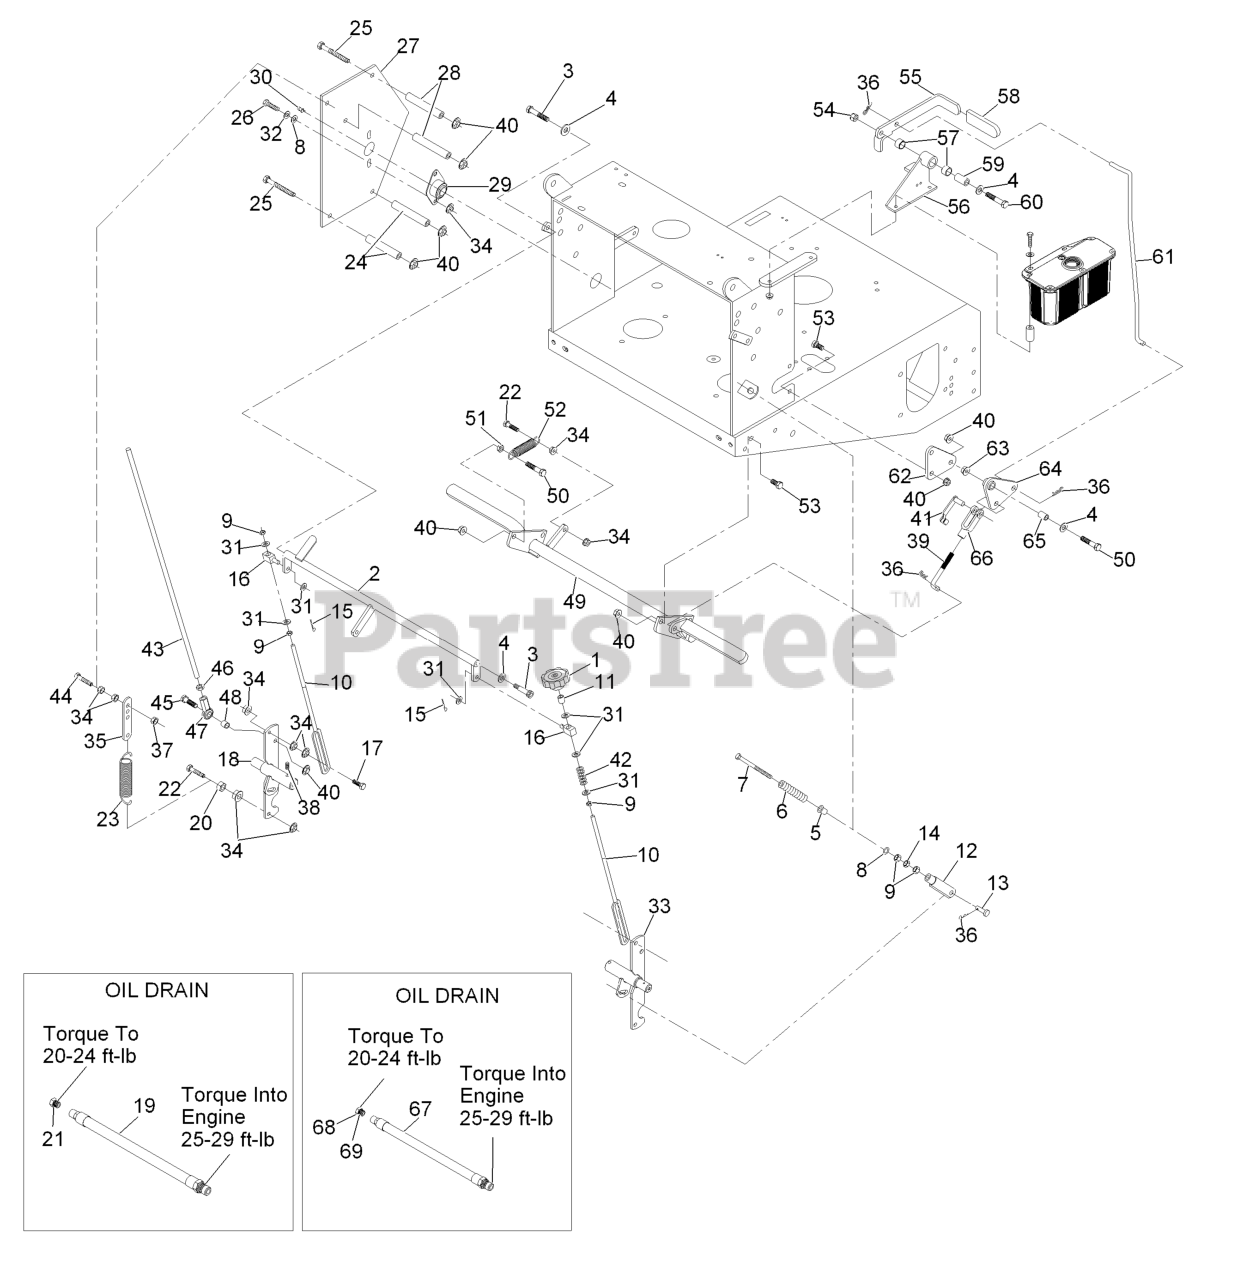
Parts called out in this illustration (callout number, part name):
1	KNOB-TRACKING
2	CRANK-CONTROL, SPEED
3	SCREW-HSH
4	WASHER-FLAT
5	BUSHING-FLANGED
6	SPRING,COMPRESSION (NEUT)
7	BOLT-RETURN, NEUTRAL
8	WASHER-FLAT
9	NUT-HEX
10	LINK-CONTROL, SPEED
12	YOKE-ADJUSTABLE
13	PIN-CLEVIS
14	NUT-JAM
15	PIN-COTTER
17	SCREW-HH
18	SHAFT-CONTROL, LH
20	NUT-JAM
22	SCREW-HH, SPECIAL
23	SPRING-EXTENSION
24	SPACER-SHIELD
25	SCREW-HH
26	SCREW-HH
27	SHIELD-CONTROL
28	SPACER-SHIELD
29	BEARING-FLANGE, SIDE
30	FITTING-GREASE
31	WASHER-PLAIN
32	WASHER-LOCK
33	SHAFT-CONTROL, RH
35	TAB-SPRING, EXTENSION
36	PIN-COTTER
37	NUT-LOCK, NI
38	SCREW-SET
39	LINKAGE-LOWER
40	NUT-HHF, WHIZ
41	PIN-SPRING, CLEVIS
42	SPRING-COMPRESSION
43	LINKAGE,DRIVE (PLT)
44	BOLT-TAP, HH
45	SCREW-HH
46	NUT-HEX JAM, LH
47	JOINT-BALL END, LH
48	SPACER-TUBE, PUMP LINK
50	SCREW-HH
51	NUT-JAM
52	SPRING-IDLER
53	SCREW-HH
54	NUT-LOCK, NI
55	LEVER,PARK BRK W/DECAL
56	BRACKET ASM
57	SLEEVE-BUSHING
58	GRIP-LEVER
59	BUSHING-PIVOT
60	SCREW-HH
61	LINKAGE-UPPER
62	BELLCRANK
64	BELLCRANK ASM
65	BUSHING-PLASTIC
66	YOKE-LINKAGE, BRAKE
67	ASM, ENGINE OIL DRAIN HOS
68	PLUG-HH
69	O-RING
